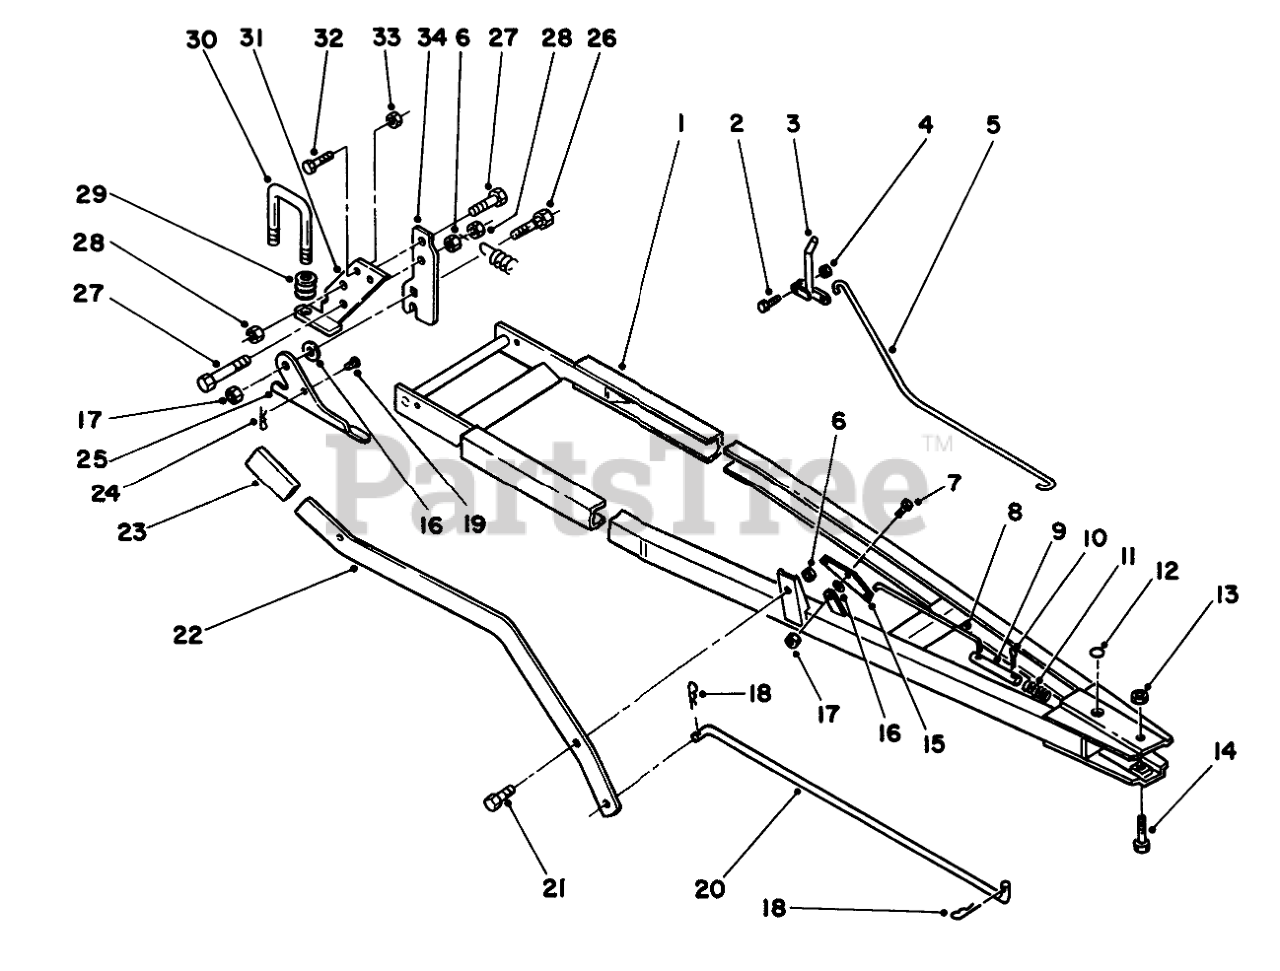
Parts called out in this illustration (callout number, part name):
1	Frame
2	SCREW-HH
3	Lever-Index
4	NUT-LOCK
5	ROD-UPPER INDEX
6	Jam Nut
7	SCREW-HH
8	ROD-LOWER INDEX
9	Index Pin
10	PIN-COTTER
11	SPRING-COMPRESSION
12	PLUG
13	Nut
14	SCREW-HH
15	Index Plate
16	WASHER-FLAT
17	NUT-LOCK, NI
18	Hairpin
19	Pin
21	SCREW-HH
22	LEVER-BLADE CONTR R
23	GRIP
24	Hairpin
25	PLATE-LATCHING
26	BOLT-CARR
27	H H C S
28	NUT-LOCK, NI
29	Washer
30	U-BOLT
31	PLATE-HITCH
32	PLATE-HITCH
32	SCREW-HH
33	NUT-LOCK, NI
34	BRACKET-HITCH
